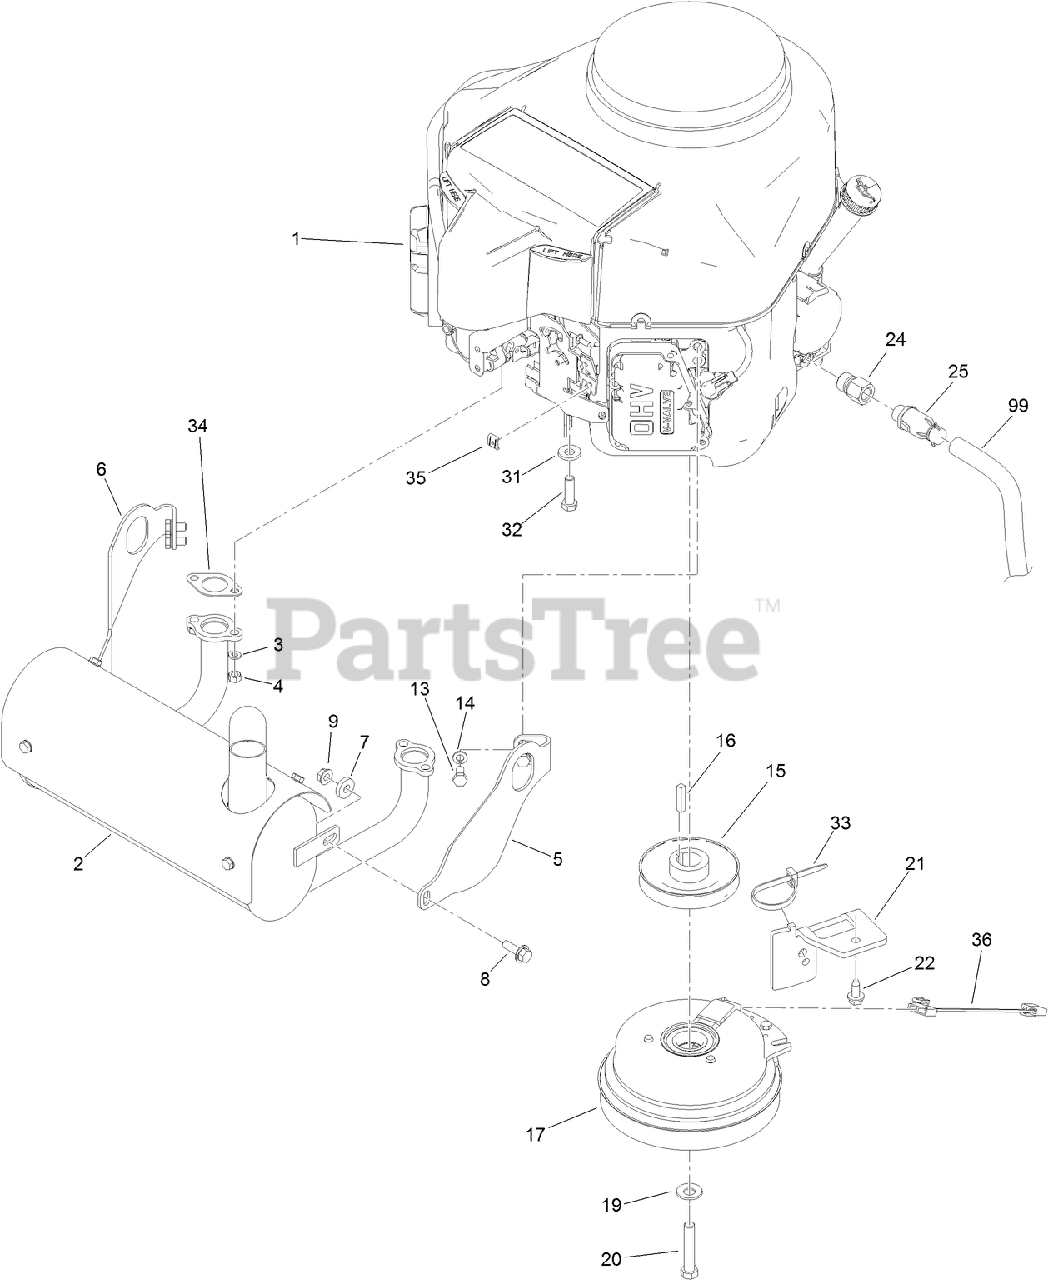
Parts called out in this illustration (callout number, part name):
2	MUFFLER
3	WASHER-LOCK
5	BRACKET-MUFFLER MOUNT, LH
6	BRACKET-MUFFLER MOUNT, RH
7	SPACER
8	SCREW-HHF
9	NUT-HF
13	SCREW-HH
14	WASHER-LOCK
15	PULLEY
17	CLUTCH
19	WASHER-SPRING
20	SCREW-HH
21	BRACKET-ANCHOR, CLUTCH
22	SCREW-HWHTF
24	Adapter
25	VALVE-DRAIN, OIL
31	WASHER-BELLEVILLE
32	SCREW-HH
33	TIE-CABLE
34	GASKET-EXHAUST
35	CLAMP-CABLE
36	HARNESS-CLUTCH
99	HOSE-DRAIN, OIL
